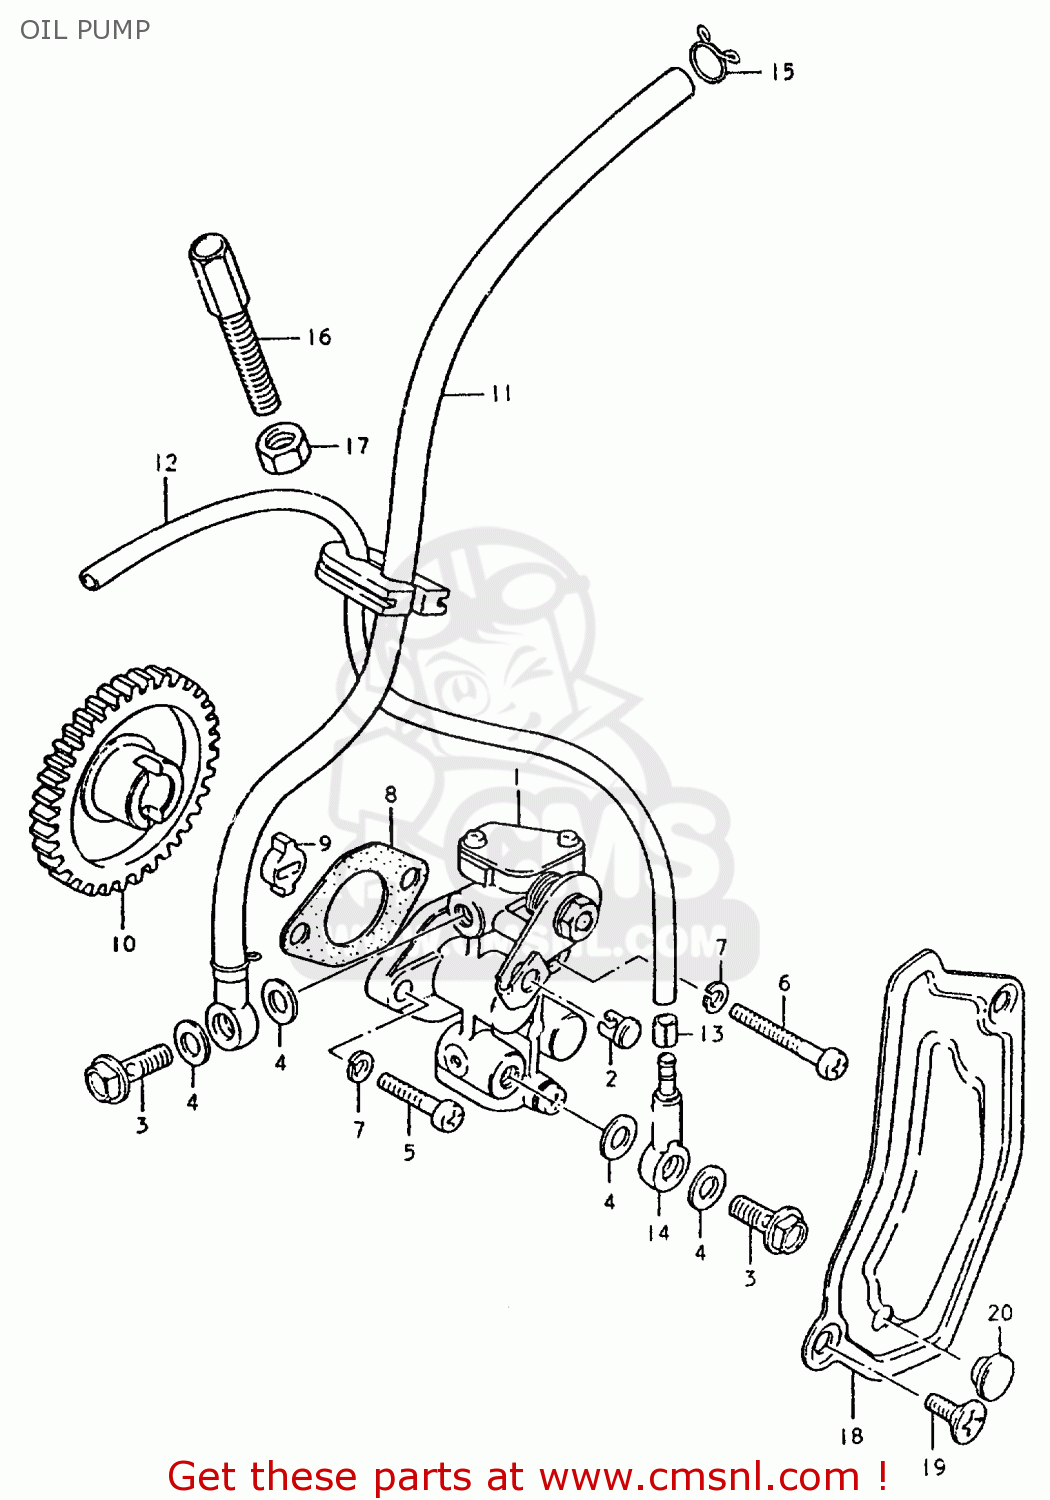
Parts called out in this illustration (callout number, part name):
1	PUMP ASSEMBLY,OIL
2	TERMINAL,CABLE
3	UNION BOLT
4	GASKET(6.2X11X1).2 (NAS)
5	SCREW
6	SCREW
7	LOCK WASHER
8	GASKET,OIL PUMP (NAS)
9	PIECE,OIL PUMP DRIVE
10	GEAR,OIL PUMP DRIVE
11	HOSE, OIL INLET
12	HOSE,OIL
13	CLIP
14	VALVE,CHECK
15	CLIP
16	BOLT
17	NUT
18	CAP, INSPECTION
19	SCREW
20	CUSHION
